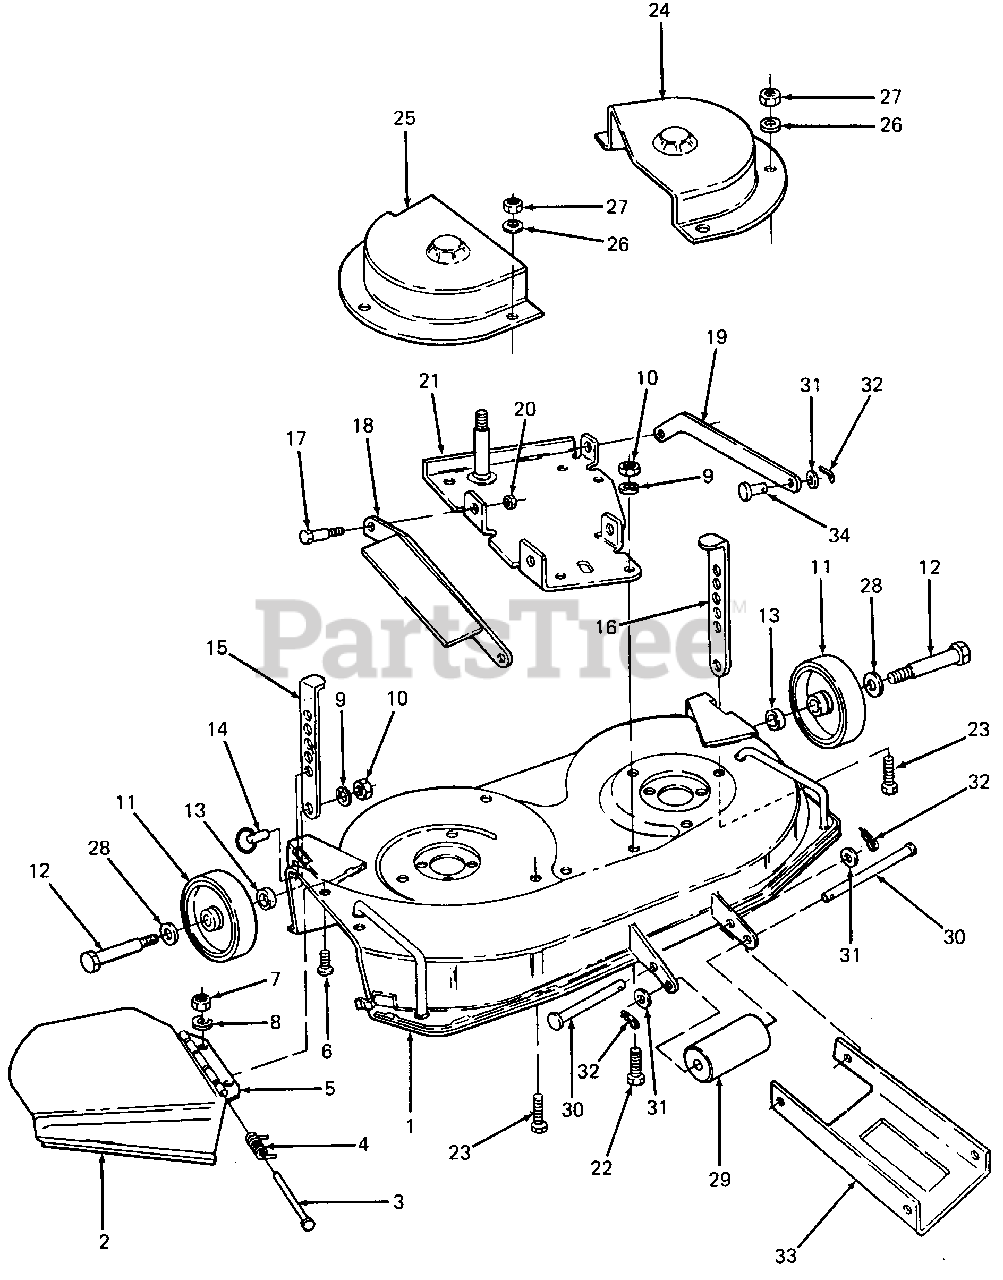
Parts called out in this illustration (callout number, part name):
2	Chute Kit w/Graphic
3	Pin, Hinge, 0.25 Dia 6.75 Long
4	Spring, Torsion, 0.29 ID X 1.14 Long
5	Bracket, Chute, 38" S.D. Deck
6	Screw, Truss Machine, 1/4-20 X 0.50 Long, Phillips
7	Nut, Hex Jam, 1/4-20
8	Washer, Lock, 1/4 Dia
9	Washer, Lock, 3/8 Dia
10	Nut, Hex, 3/8-16 GR5
11	Wheel, Gage, 5" Dia
12	Bolt, Shld, 0.50 Dia X 1.62 Long X 3/8-16
13	Spacer, 0.385 X 0.75 X 0.75 Long
14	Pin, Clevis, w/Detent Ball
15	Bar, Height Adjustment, RH
16	Bar, Height Adjustment, LH
17	Bolt, Shld, 0.50 Dia X 3/8-16
18	Deck Link Assembly, RH
19	Deck Link, LH
20	L-Nut, Hex Cent, 3/8-16 GR5
23	Screw, Hex Head Cutting, 5/16-18 X 0.62 Long
24	Cover, Belt, LH
25	Cover, Belt, RH
26	Washer, Flat, 0.34 X 0.68 X 0.06
27	Nut, Hex, 5/16-18 GR5
28	Washer, Flat, 0.510 ID X 1.12 OD X 0.100 Thk
29	Roller, Front
30	Pin, Clevis, 1/2 X 7.68
31	Washer, Flat, 0.510 X 1.0 X 0.06
32	Pin, Internal Cotter
33	Bracket, Deck Front Support
34	Pin, Lift Bracket
